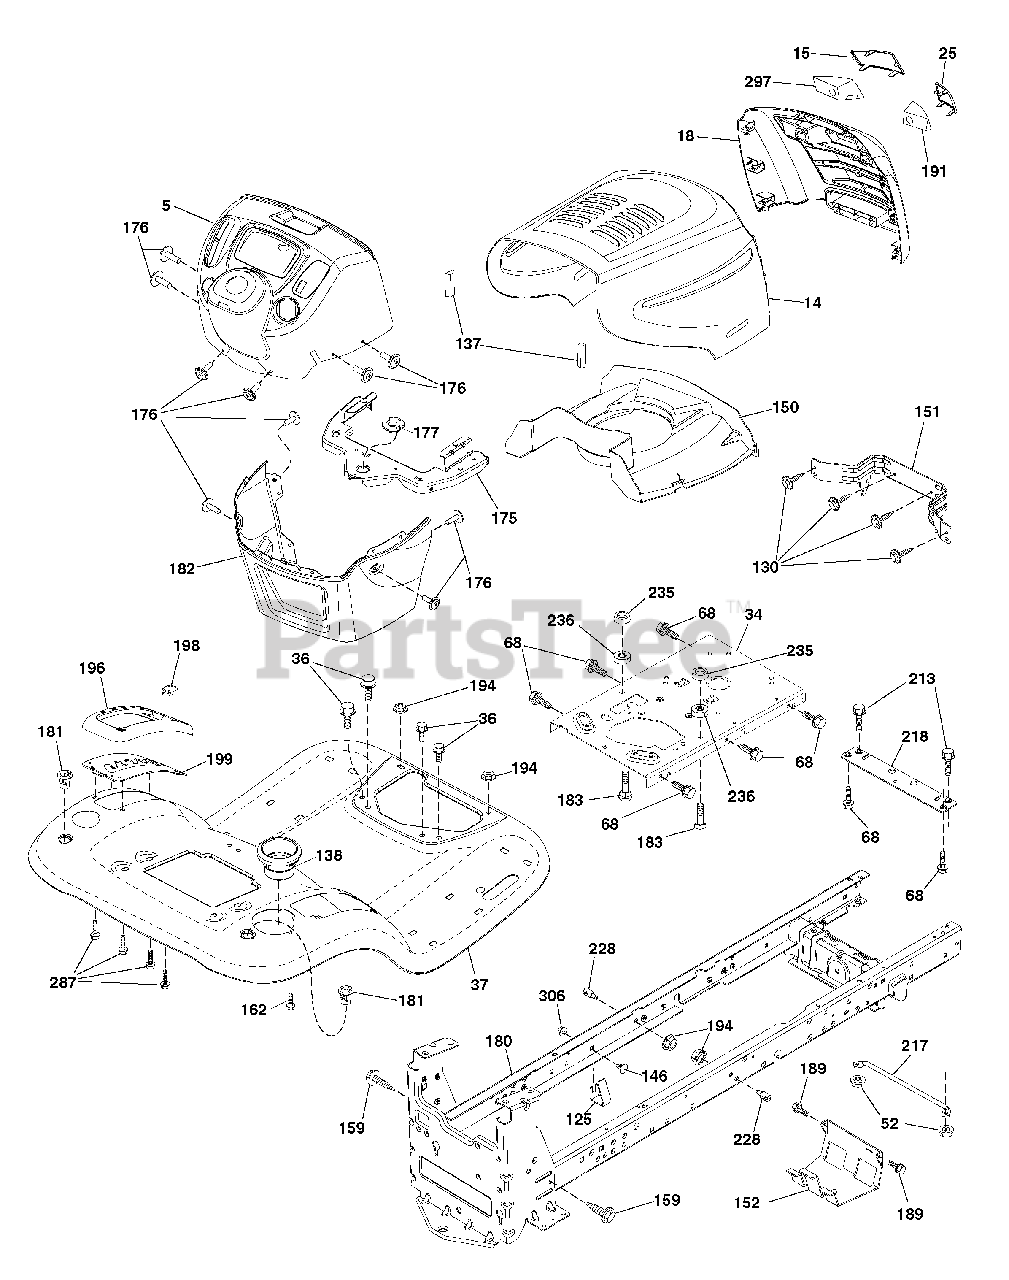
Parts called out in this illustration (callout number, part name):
5	Dash Upper Tex Elite
14	Hood Pnt Elite
15	Lens LH
25	Lens RH
34	Plate Engine Welded Chassis
36	Screw 5/16-18 X 3/4 Smgml Tap/R
52	Nut, Hex, Crownlock 5/16-18
68	Screw Thdrol 5/16-18 X 1/2 Tytt
125	Clip Fuel Line
137	Bumper Hood Large 1 75"
138	Cupholder
150	Air Duct
151	Bracket Pivot Lasr/Elte/Husqlt
152	Shield Browning W/Tex
159	Screw Hexwsh 3/8-16 X 3/4
162	Screw Hex Wsh Hi-Lo 1/4 X 1/2 Unc
175	Crossmember Lt
176	Screw #10-24X5/8 Rnd Qudrx Gim
177	Bushing Steering Yt/Gt
180	Chass Wldmt Tl 12 Ga/2Pc
181	Bushing Mnt Fend Crgo Blk Tex
182	Dash Lower Lt Ccs
183	Bolt 5/16-18 X 1-1/4
189	Screw 5/16-18 X 3/4 Smgml Tap/Bl
191	Insert Lens Rflct RH
194	Nut, Lock Hex Flange 5/16-18 Unc
196	Console Deck Lift
198	Indicator Deck Lift
199	Plate Deck Lift
213	Bolt, Hex Head 5/16-18 X 3/4
217	Rod Pivot Hood
218	X-Piece Hood Stop Non/Stealth
228	Stud Fastner W/'D'anti-Rotatio
235	Spacer Fender
236	Nut Center Lock 5/16-18 Unc
287	Screw Hex Washead 1/4-20 X 3/8
297	Insert Reflective LH
306	Nut Lock
